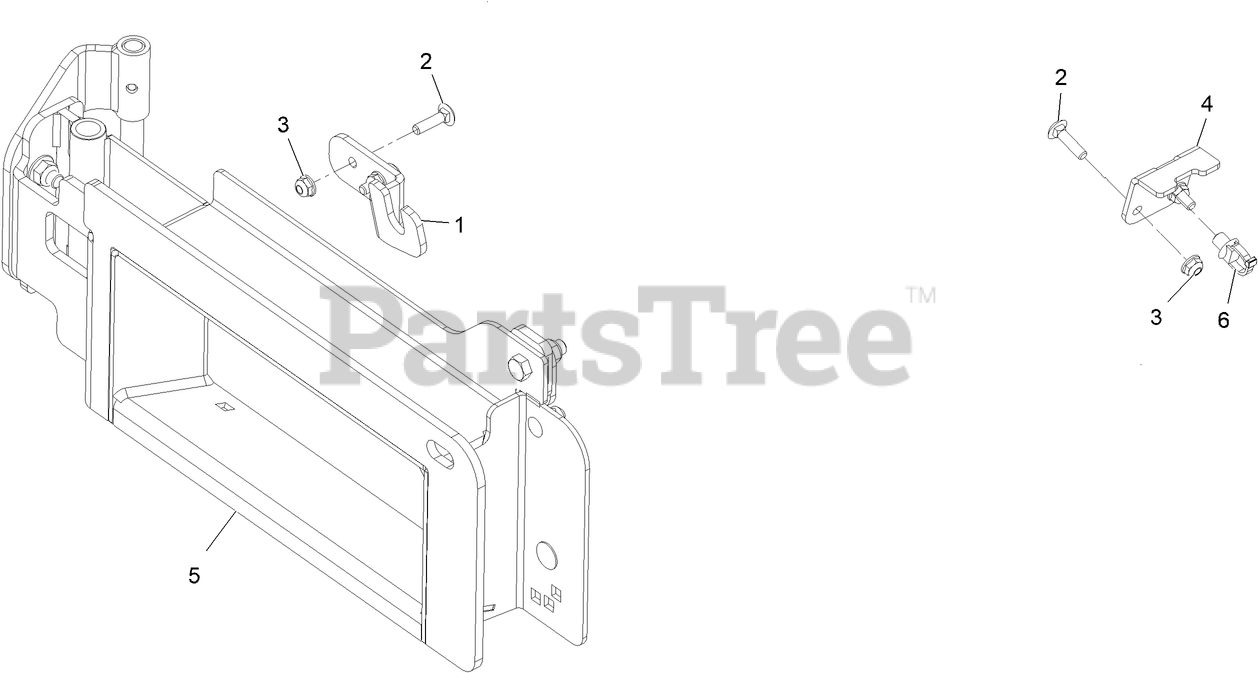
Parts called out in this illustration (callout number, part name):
1	BRKT-OCD CABLE
2	SCREW-CARR
4	BRKT-CABLE
5	KIT-ADAPTOR, ACCY. (SERIES 3)
6	CLIP-TIE
